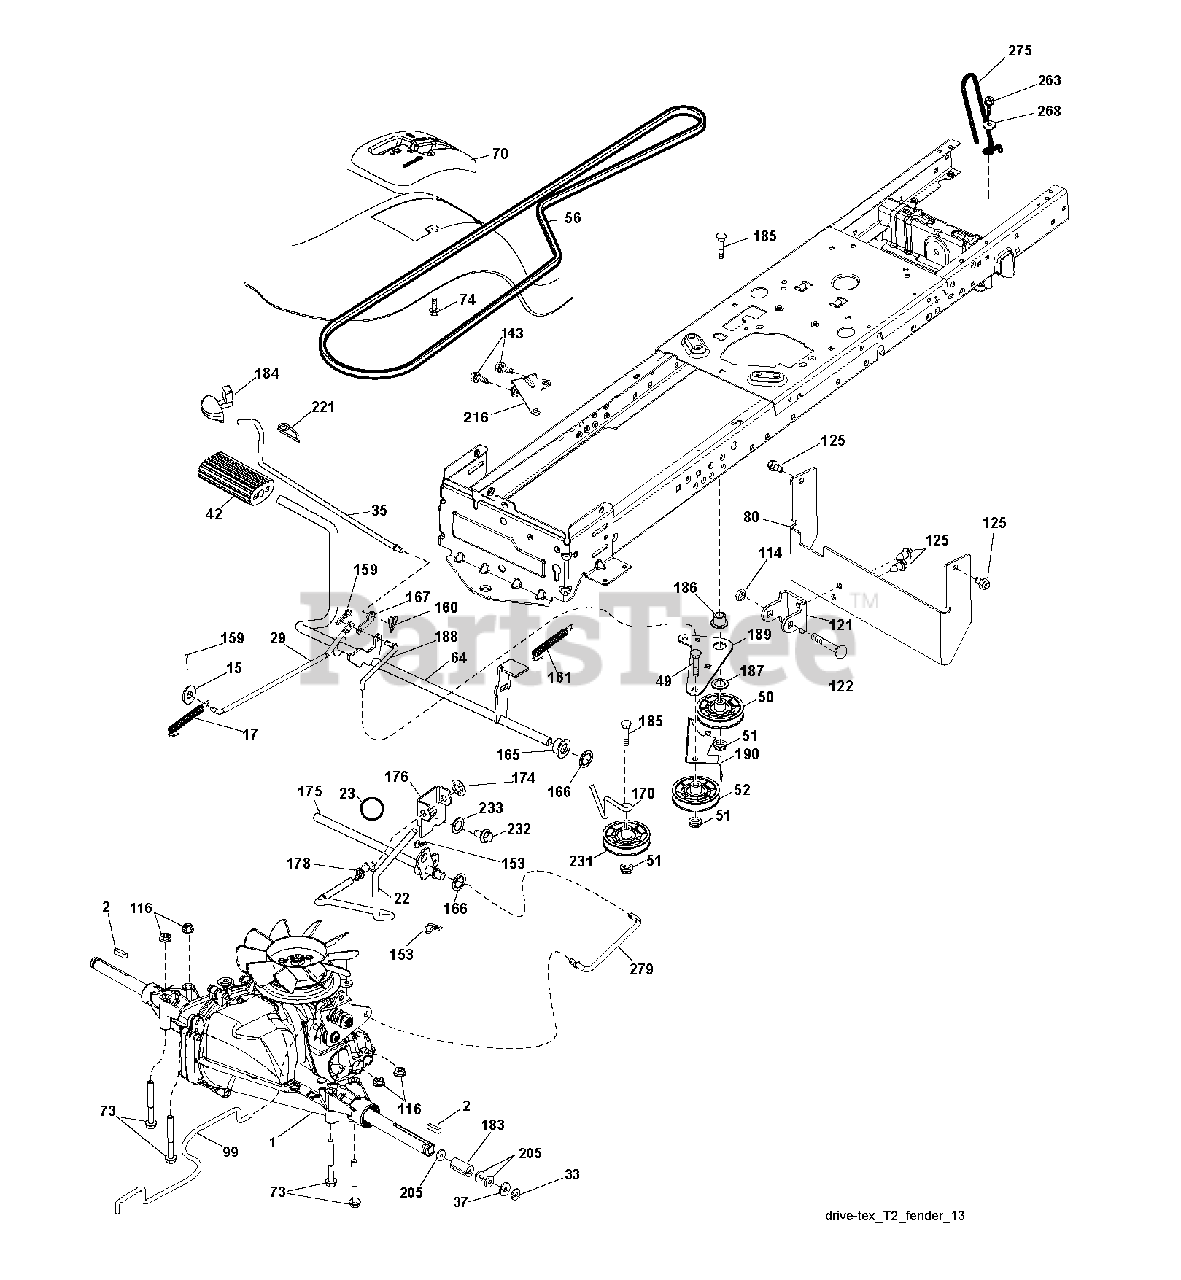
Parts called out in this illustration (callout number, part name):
2	SQUARE KEY
17	SPRING.BRAKE.HG3000/3500
22	ROD.SHIFT.FENDER.TLT.2006
23	KNOB.DUCKHEAD.1/2
29	ROD.BRAKE.T2.TEX
33	E-RING LT
35	ROD, BRAKE, PARK
42	PEDAL COVER T
49	BOLT
50	IDLER.FLAT.910.OFFSET
51	NUT LOCK FLG 3/8-16 UNC
52	IDLER.V-GROOVE.910.OFFSET
64	SHAFT.ASM.PEDAL.BRAKE.
70	CONSOLE.SHIFT.STL.HYD.BLACK
73	BOLT HEX 5/16-18 GR 5
74	SCREW.HI-LO.CONSOLE
80	STRAP.TORQUE.FS.T2
99	ROD.ASM.BYPASS.SPRING.T2.FS
114	NUT.71038.31-18.HEX.NYLOCK
116	NUT LOCK HEX FLANGE 5/16-18
121	BRACKET STRAP TORQUE
122	BOLT.5/16-18X2.5
125	SCREW
153	RETAINER M
159	COTTER PIN
160	RETAINER CLIP
161	SPRING, RETURN LT
165	BUSHING.SHAFT.BRAKE.HAND
166	NUT.PUSH.625.2006
167	LATCH.BRAKE.SPRING
170	KEEPER.CENTER SPAN.1.688
174	NUT.PUSH.500.2006
175	SHAFT.ASM.SHFT.T2.TLT
176	ARM.CLEVIS.ROD.SHIFT
178	SPRING.SHIFT.GT2006
183	SPACER, AXLE PVST
184	HANDLE PARKING BRAKE
186	SPACER.RETAINER
187	WASHER 12/32X2X10GA
188	LINK.CLUTCH.GROUND.DRIVE
189	BELLCRANK.GROUND.DRIVE.TEX.
190	KEEPER.BELLCRANK.DRIVE
216	BRACKET.PULLEY.IDLER.W/TEX
221	RETAINER.SPRING.CLIP.H
231	IDLER.V-GROOVE.1.688.OFFSET
232	BOLT FIN HEX 7/16-14 X 1
233	WASHER SERRATED
263	SCREW, 3/8-16X3/4
268	WASHER
279	LINK SHIFT
